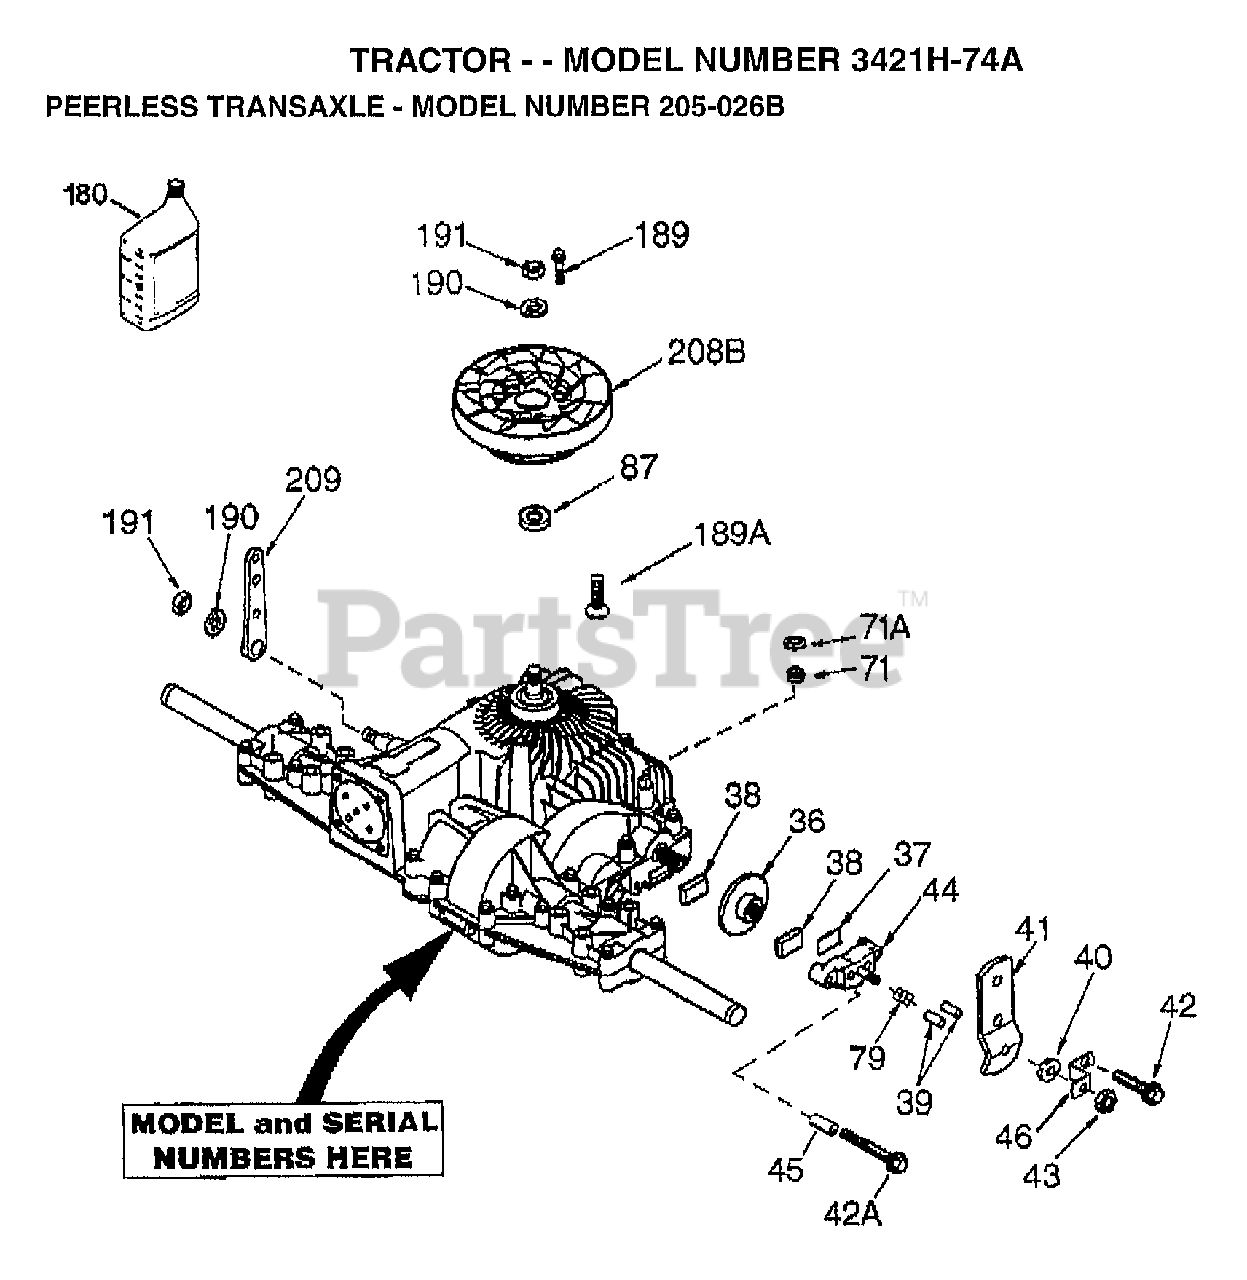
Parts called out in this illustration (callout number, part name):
37	PLATE BRAKE PAD
41	BRAKE LEVER
42	SCREW, 1/4-20 X 1-1/4
42A	SCREW, 1/4-20 X 2-1/4
43	LOCKNUT 5/16-24
44	HOLDER BRAKE PAD
46	BRAKE LEVER BRACKET
71	SEAL SQUARE CUT
180	GEAR OIL 80W90
189	DRIVE SCREW
208B	FAN/COUPLING
209	CONTROL LEVER
